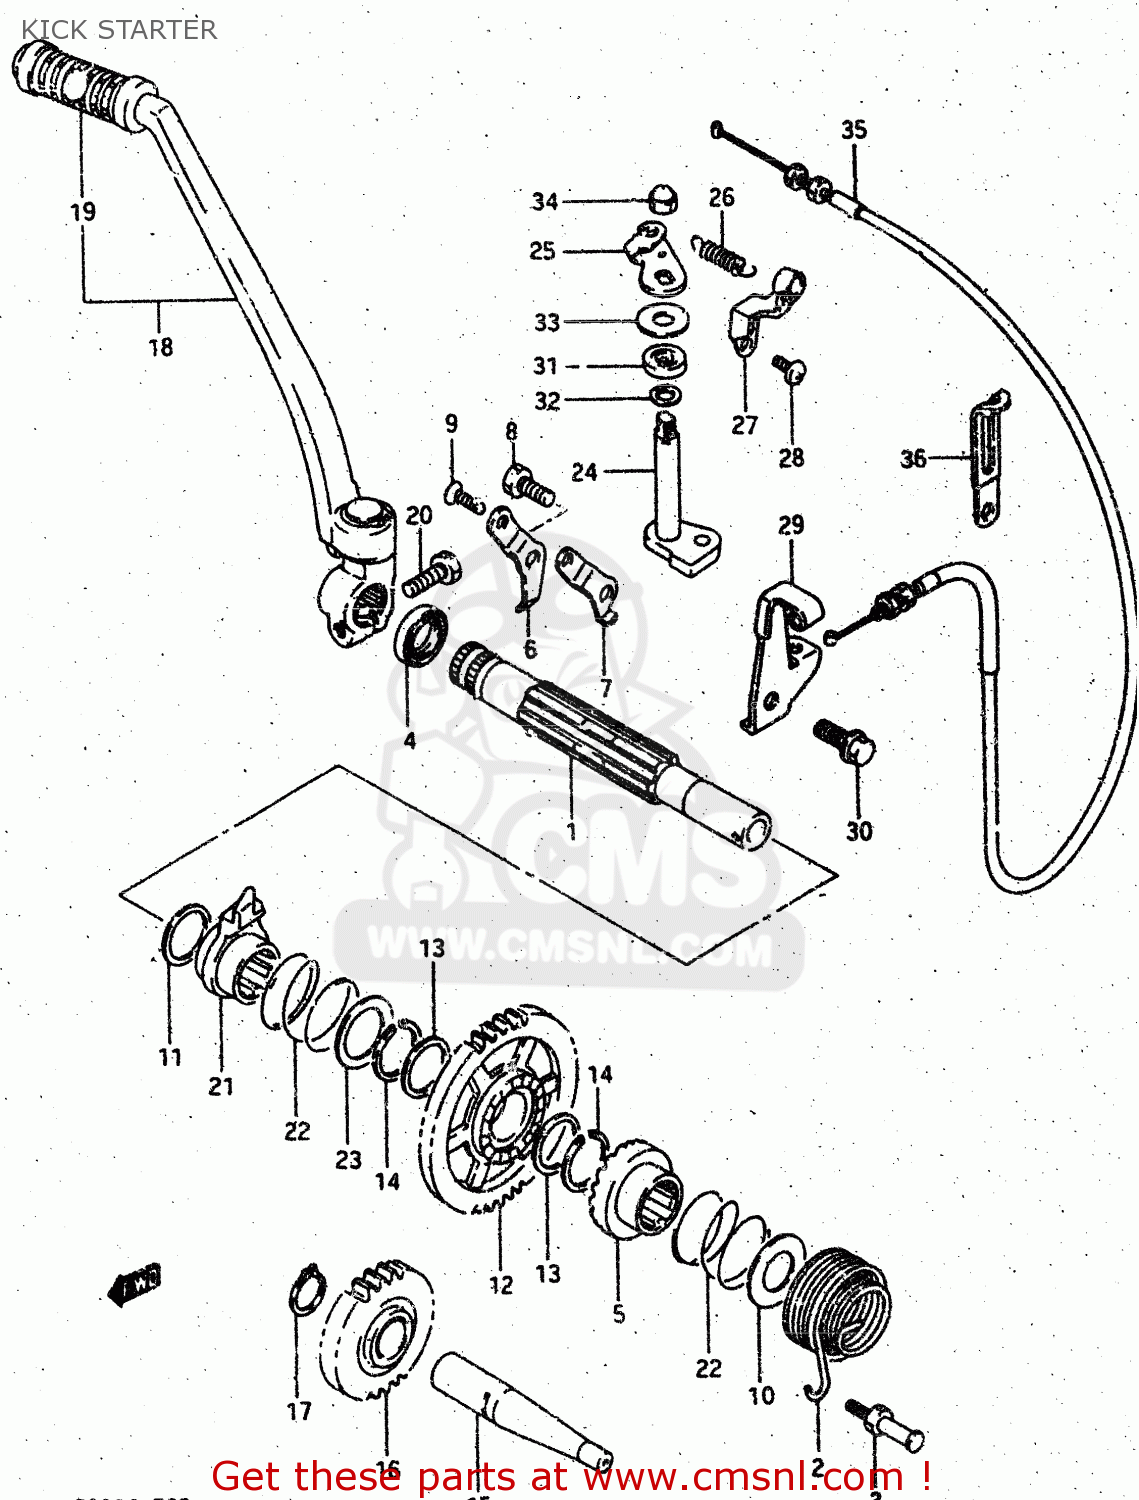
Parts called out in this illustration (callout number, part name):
1	SHAFT,KICK STARTER
2	SPRING
3	BOLT,KICK SHAFT SPRING
4	SEAL,OIL(20X27X6)
5	STARTER,KICK
6	GUIDE,KICK STARTER
7	STOPPER,KICK STARTER
8	BOLT
9	SCREW M6X1X16
10	WASHER
11	WASHER,THRUST
12	GEAR,KICK STARTER DRIVE
13	SHIM
14	CIRCLIP
15	SHAFT,KICK STARTER IDLE
16	GEAR,KICK STARTER IDLE
17	CIRCLIP
18	LEVER ASSEMBLY,KICK STARTER
19	RUBBER,KICK STARTER PEDAL
20	BOLT 8X25
21	CAM,DECOMPRESSION
22	SPRING
23	WASHER
24	SHAFT,DECOMP CAM FOLLOWER
25	ARM,DECOMPRESSION SHAFT
26	SPRING
27	HOLDER,DECOMPRESSION CABLE NO
28	SCREW
29	HOLDER,DECOMP CABLE NO.2
30	BOLT, LOWER
31	OIL SEAL
32	WASHER
33	WASHER(10.5X24X1)
34	NUT,M8X1.25X12
35	CABLE,KICK STARTER DECOMP
36	CLAMP L:35
